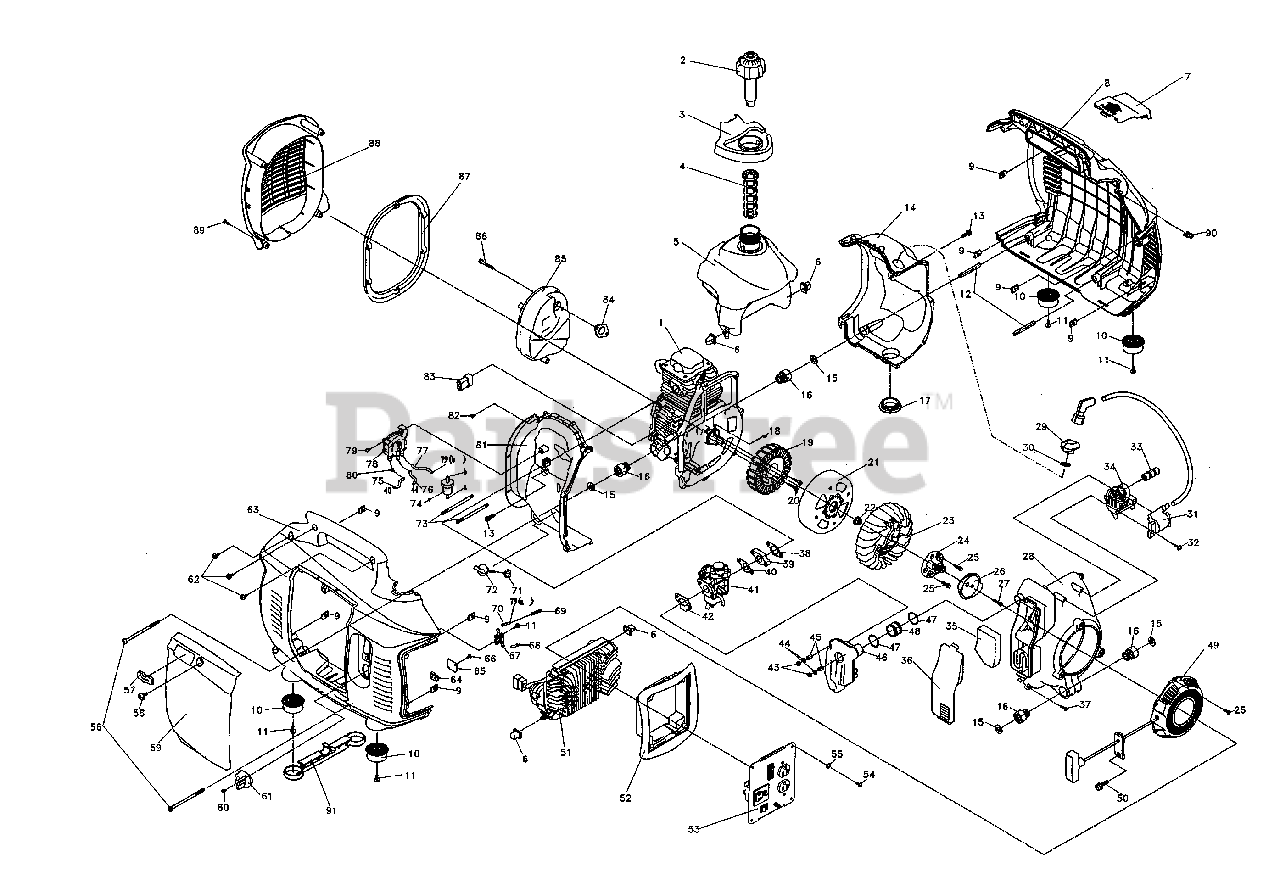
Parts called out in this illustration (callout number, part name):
2	CAP ASSY., FUEL TANK (RED)
3	COVER, FUEL FILLER PORT
4	CUP, FUEL FILTER
5	TANK, FUEL (PLASTIC)
6	BLOCK, SHOCK ABSORBER
7	COVER, LOWER SHELL
8	SHELL, LOWER
9	CLIP, SCREW
10	FEET, VIBRATION MOUNTS
11	RECESSED PAN HEAD SCREW, ST6. 3X19
12	PIN, ALIGNMENT
13	BOLT, HEX, W/ FLANGE M6X12
14	CASING, LOWER, ENGINE
16	SLEEVE, DAMPING
17	SEAL COVER, OIL SENSOR
18	KEY, WOODRUFF, 3X5X13
19	STATOR ASSY.
20	BOLT, HEX, W/ FLANGE M5X30
21	FLYWHEEL/ROTOR ASSY.
22	NUT, HEX/FLANGED M10X1.25-8
24	JAW SEAT, STARTING
25	BOLT, HEX,FLANGED, M6X16
26	COUPLER, STARTING JAW
27	BOLT, HEX/FLANGED, M8X14
28	COVER ASSY, COWLING AND INLET
29	PLUG, RUBBER
30	O-RING, RUBBER, 20X1.8
31	COIL, IGNITION
32	TAPPING SCREW, RECESSED PAN/HD STR. 8X25
33	PIN, MOUNTING (POTHOOK PILLAR)
35	CLEANER, AIR
36	COVER, AIR FILTER
37	SCREW, PAN HEAD,TAPPING STR.8X32
38	GASKET, CARBURETOR (B) OUT
39	BLOCK, CARBURETOR SPACER (CUSHION)
40	CARBURETOR, SEAL GASKET A (OUT)
41	REGULATING ASSY. CARBURETOR
42	GASKET, CARBURETOR IN
43	NUT, HEX/ FLANGED, M5
44	WASHER, FLAT
45	PIN, ALIGNMENT, FILTER CASE LINER
46	CASE ASSY., FILTER
47	SPRING CLIP
48	ADAPTER SLEEVE, FILTER
49	STARTER, RECOIL ASSY.
50	BOLT, HEX HEAD W/WASHER, M5X12
51	INVERTER ASSY
52	FRAME, FRONT PANEL
53	PLATE ASSY, CONTROL
54	SCREW, PAN HEAD, RECESSED, M5X25
55	WASHER, FLAT 5
56	SCREW, PAN HEAD RECESSED, M6X120
57	SEAL COVER, LOWER SHELL
58	SCREW, M6X14
59	COVER, UPPER SHELL
60	SCREW, PAN HEAD M4X12
61	TURN KNOB, FUEL SWITCH
62	SCREW, PAN HEAD, RECESSED, M6X14
63	SHELL, UPPER
64	SWITCH, IGNITION, ON/OFF
65	COVER, SWITCH
66	SCREW, RECESSED PAN HEAD/ ST4.2X9.5 TAPPING
67	VALVE, FUEL
68	HOSE, OIL DISCHARGE
69	SHIELD, PIPE SPRING
70	HOSE, FUEL PUMPI OIL INJ.
72	COVER, OIL W/DIPSTICE
73	STUD/BOLT
74	FILTER, FUEL
75	PIPE, FUEL PUMP OUTLET
76	GASPIPE, FUEL PUMP
77	PIPE-B, FUEL PUMP INLET
78	PUMP ASSY., FUEL
79	SCREW, PAN HEAD , RECESSED,
80	CLAMP, FUEL HOSE
81	CASING, UPPER ENGINE
82	SCREW, TAPPING-PAN HEAD RECESSED ST4.2X16
83	SLEEVE, RESPERATOR ADAPTOR
84	SHIM, MUFFLER
85	MUFFLER ASSY.
86	BOLT, HEX HEAD, FLANGED, M6X55
87	RUBBER SEAL, BACK WINDOW
88	WINDOW, BACK (EXHAUST COVER)
89	SCREW, RECESSED PAN HEAD/ M5X20
90	RETAINING CLIP, SHELL
91	BAFFLE, THERMAL
